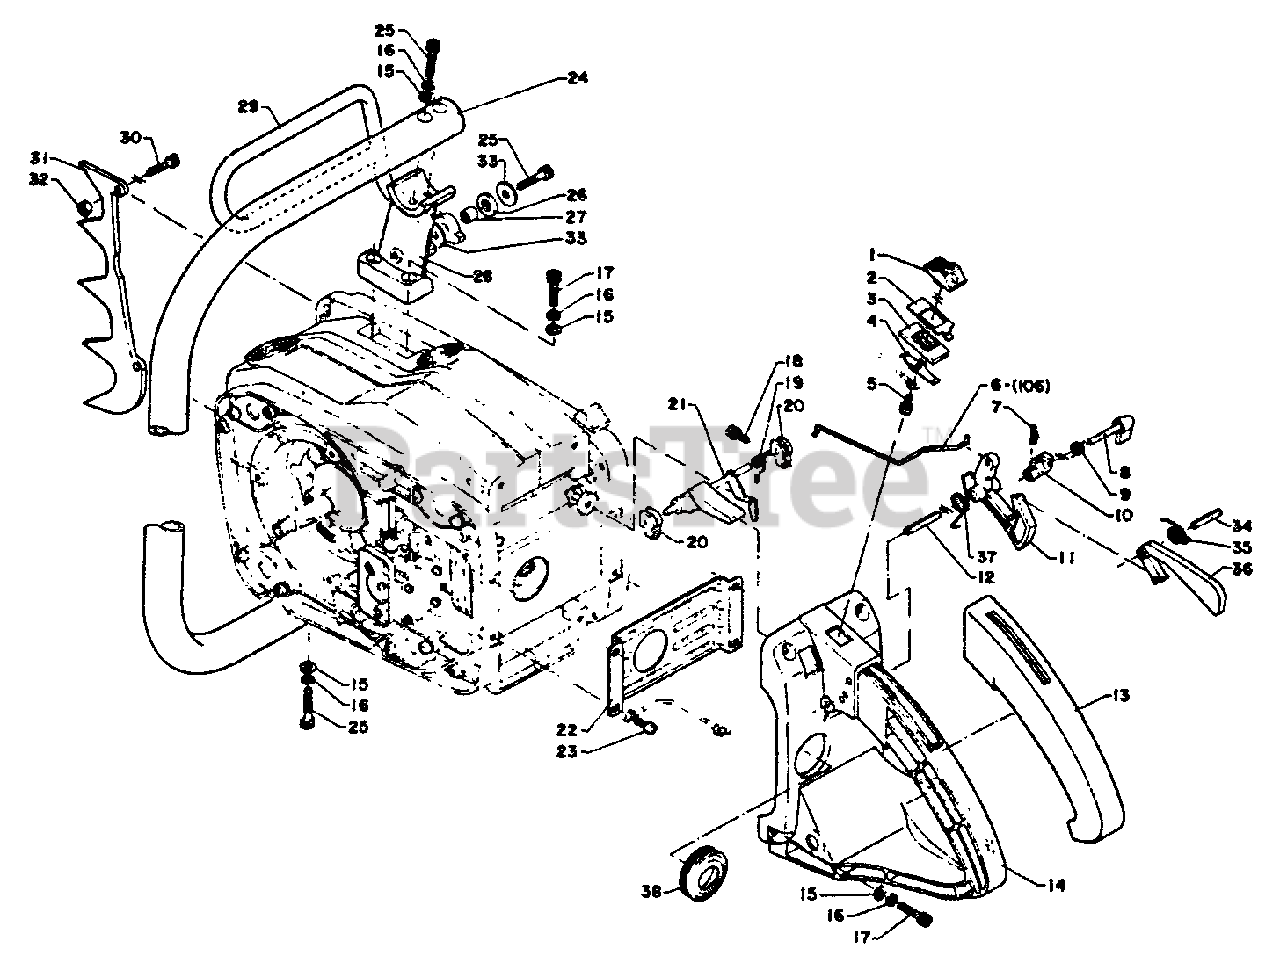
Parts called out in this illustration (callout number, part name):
1	SWITCH, IGNITION
2	PLATE, SWITCH
3	GUIDE, SWITCH
4	CONTACT, SWITCH
5	SCREW - 4×10
6	ROD, THROTTLE
7	PIN, LOCKING
8	LEVER, THROTTLE
9	SPRING, THROTTLE LOCK
10	LOCKOUT, TRIGGER
11	TRIGGER, THROTTLE
12	PIN, SPRING - 5×28
13	RIGHT HANDLE RUBBER
14	RIGHT HANDLE
15	WASHER
16	WASHER, SPRING 5
17	BOLT 5×20
18	SCREW 4×12
19	LEVER SPRING
20	BUSHING
21	PUMP LEVER
22	SUPPORT, CRANKCASE
23	SCREW 4×14
24	HANDLE - FRONT
25	BOLT 5×25
26	WASHER
27	GUARD
28	LEFT HANDLE SUPPORT
29	GUARD
30	SCREW - 5×15
31	BUMPER, SPIKED
32	LOCKNUT - 5
33	WASHER 5.5×18×1
34	PIN, SPRING - 4×25
35	SPRING, LOCKOUT RETURN
36	LOCKOUT, THROTTLE
37	SPRING, TRIGGER
38	COVER, SPARK PLUG CAP
